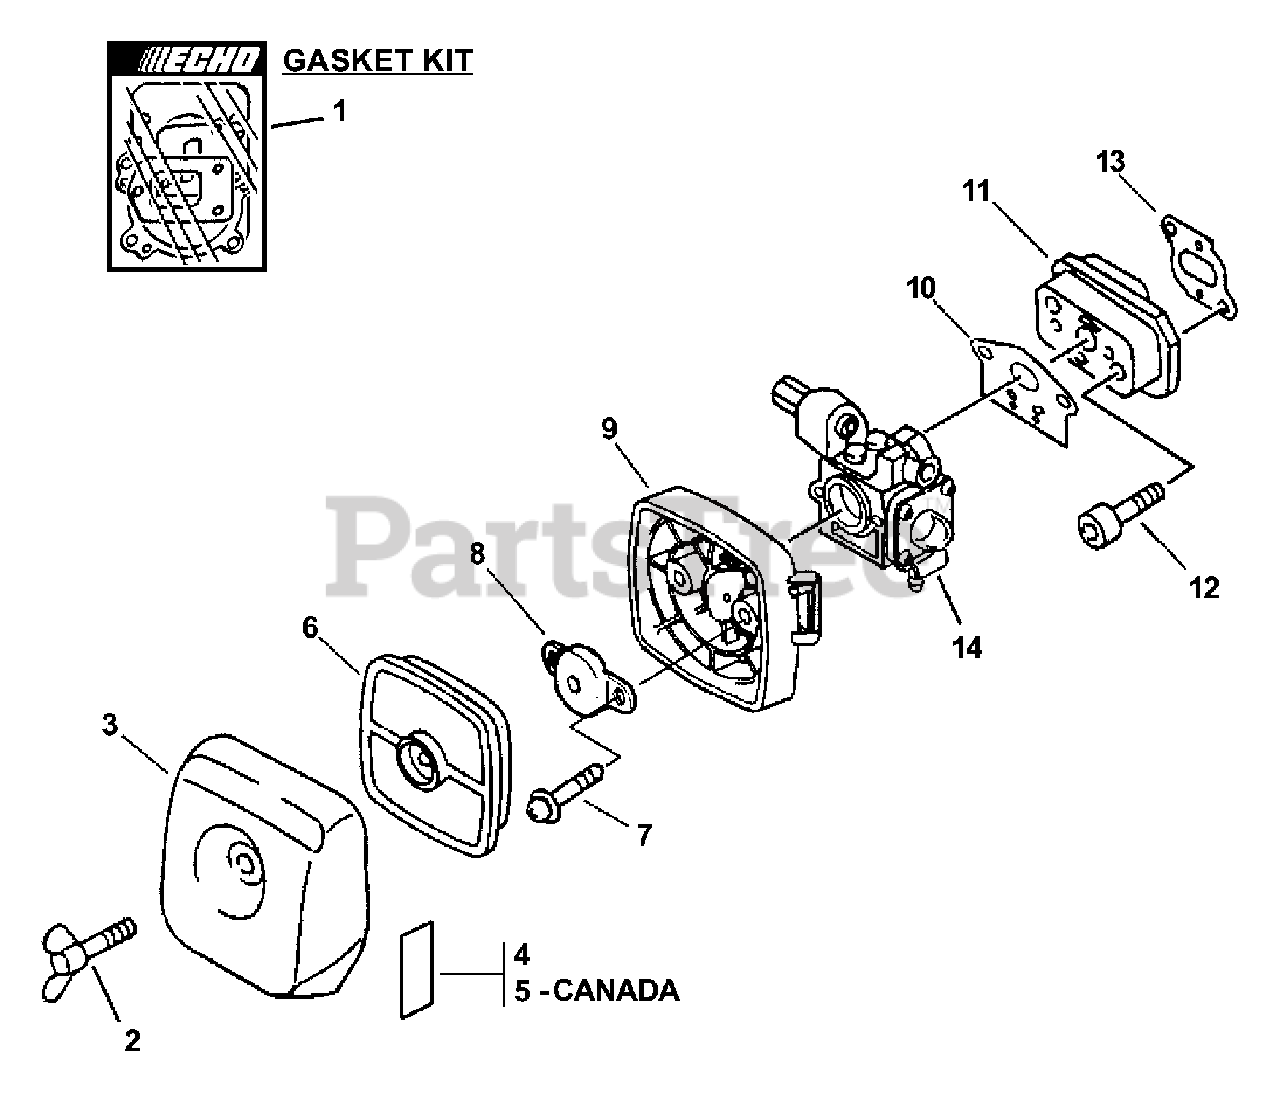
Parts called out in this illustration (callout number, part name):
1	GASKET KIT
2	BOLT, WING 5×20
3	COVER, AIR FILTER - BLACK
4	LABEL, CHOKE
5	LABEL, CHOKE
6	FILTER, AIR - SINGLE LAYER
7	SCREW 5×60
8	PLATE, PREVENT
9	CASE, AIR FILTER - BLACK
10	GASKET, CARBURETOR
11	INSULATOR, INTAKE
12	BOLT 5×25
13	GASKET, INTAKE
14	CARBURETOR
